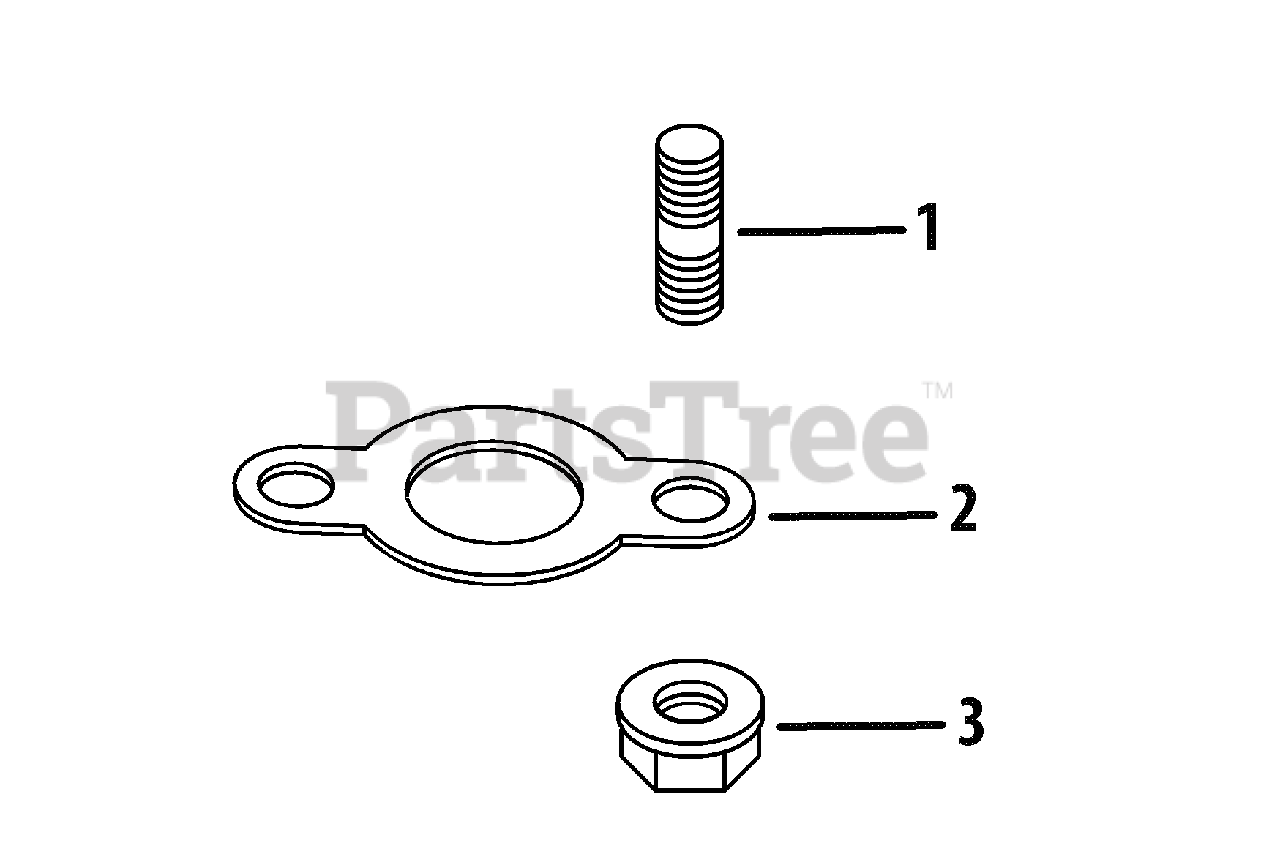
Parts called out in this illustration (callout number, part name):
1	Stud, M8X1.25X33
2	Gasket, Exhaust
3	Nut, Flg M8X1.25
